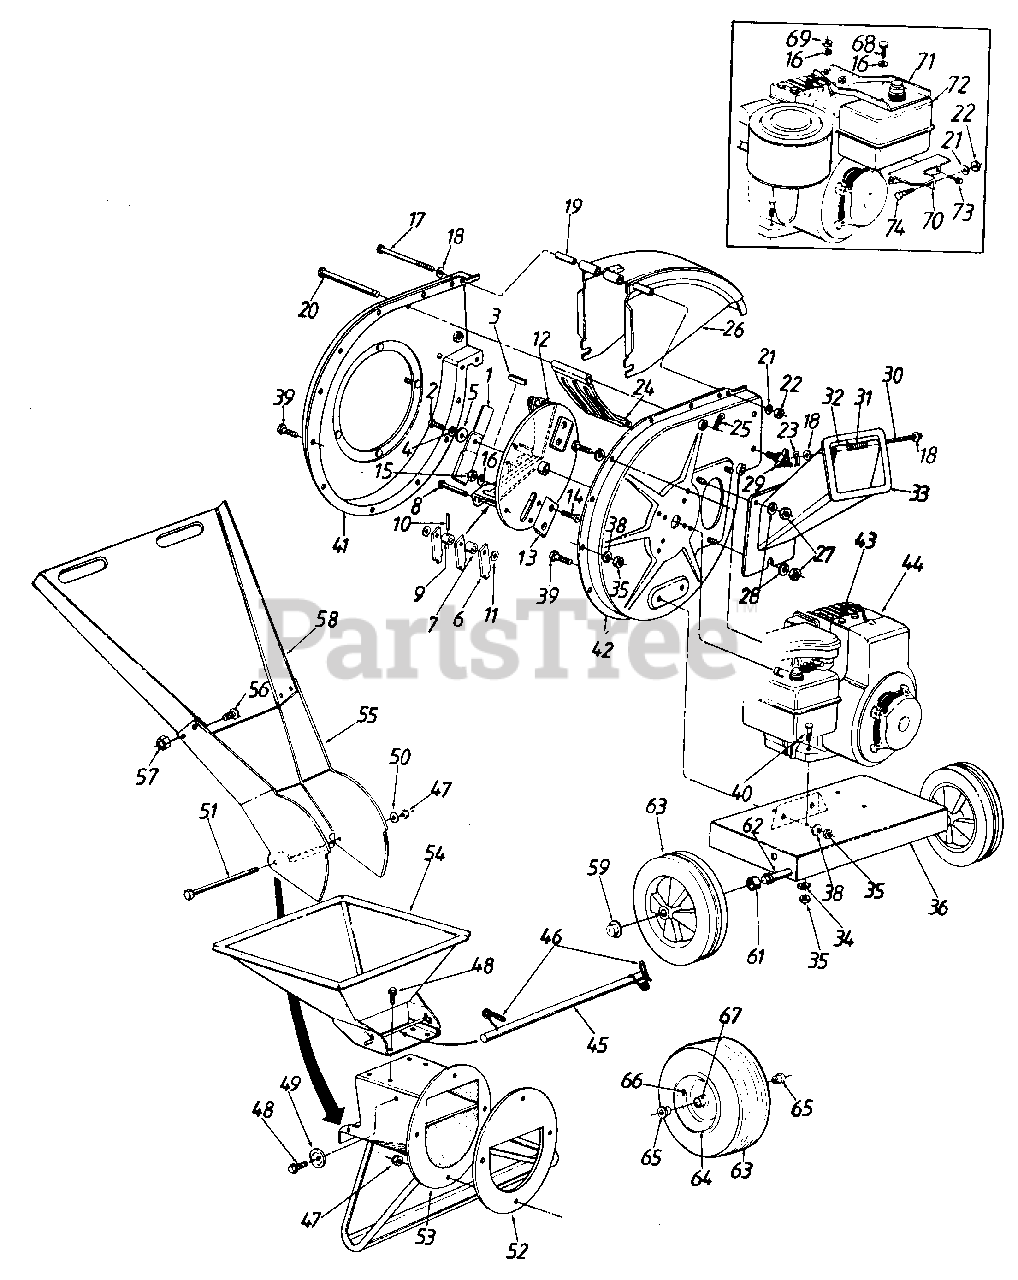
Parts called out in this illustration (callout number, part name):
3	KEY-SQ 1/4 X 2.00
4	WASHER-HDL 3/8
5	WASHER-FL-HOND .410ID X 1.255X.162
6	FLAIL
7	SPACER-FLAIL
8	PIN-CLEVIS
9	SPACER
10	PIN-SPRING ROLL 5/32 X 1.12
11	WASHER-FL-.531 ID X .93 OD X .090
12	KIT-IMPELLER ASSY
13	BLADE-CHIPPER
14	SCREW-FLAT HD
15	NUT-5/16X24
16	WASHER-LOCK-5/16
17	BOLT-HEX 1/4-20 X 4 LG
18	WASHER-FL-.344 ID X .88 OD X .063
19	SPACER-.260 X .373 X 1.66
20	PIN-CLEVIS
21	LOCK WASHER 1/4 DIA
22	NUT-HEX 1/4-20
25	PIN-INTERN COT
27	NUT-HEX 5/16-18
28	WASHER-BELL .337 X .867 X .057
29	KNOB-THREE ARM
30	ROD-CHIPPER DOOR
31	SPRING-TORSION
35	NUT-HEX 5/16-18
38	WASHER-LOCK-5/16
39	SCREW-HEX 5/16 X 3/4
40	SCREW-HEX 5/16-18 X 1.75
43	INSULATOR-SPARK PLUG
45	BAR-RELEASE
46	SPRING-TORSION
47	NUT-HEX INS L-5/16-18
48	SCREW-HEX WASH SF TAPP
49	WASHER-STOP
50	WASHER-FL-.344 X .62
51	SCREW-HEX 5/16-18 X 8.25
52	PLATE-BACK-UP
53	GUIDE ASSY-INLET
56	SCREW-TRUSS MACH 1/4-20 X .50
57	NUT-HEX CENTER L-1/4-20
61	SPACER
62	AXLE-SHREDDER 8 HP
64	WHEEL RIM
65	BEARING-FLANGE
66	VALVE-TUBELESS AIR
67	FITTING-GREASE
68	SCREW-HEX 5/16-18 X .62
69	NUT-HEX 5/16-18
70	BRACKET-TANK SUPPORT
73	SCREW-HEX WASH HD AB-TAPP #8 X .38
74	SCREW-HEX 1/4-20 C .62
